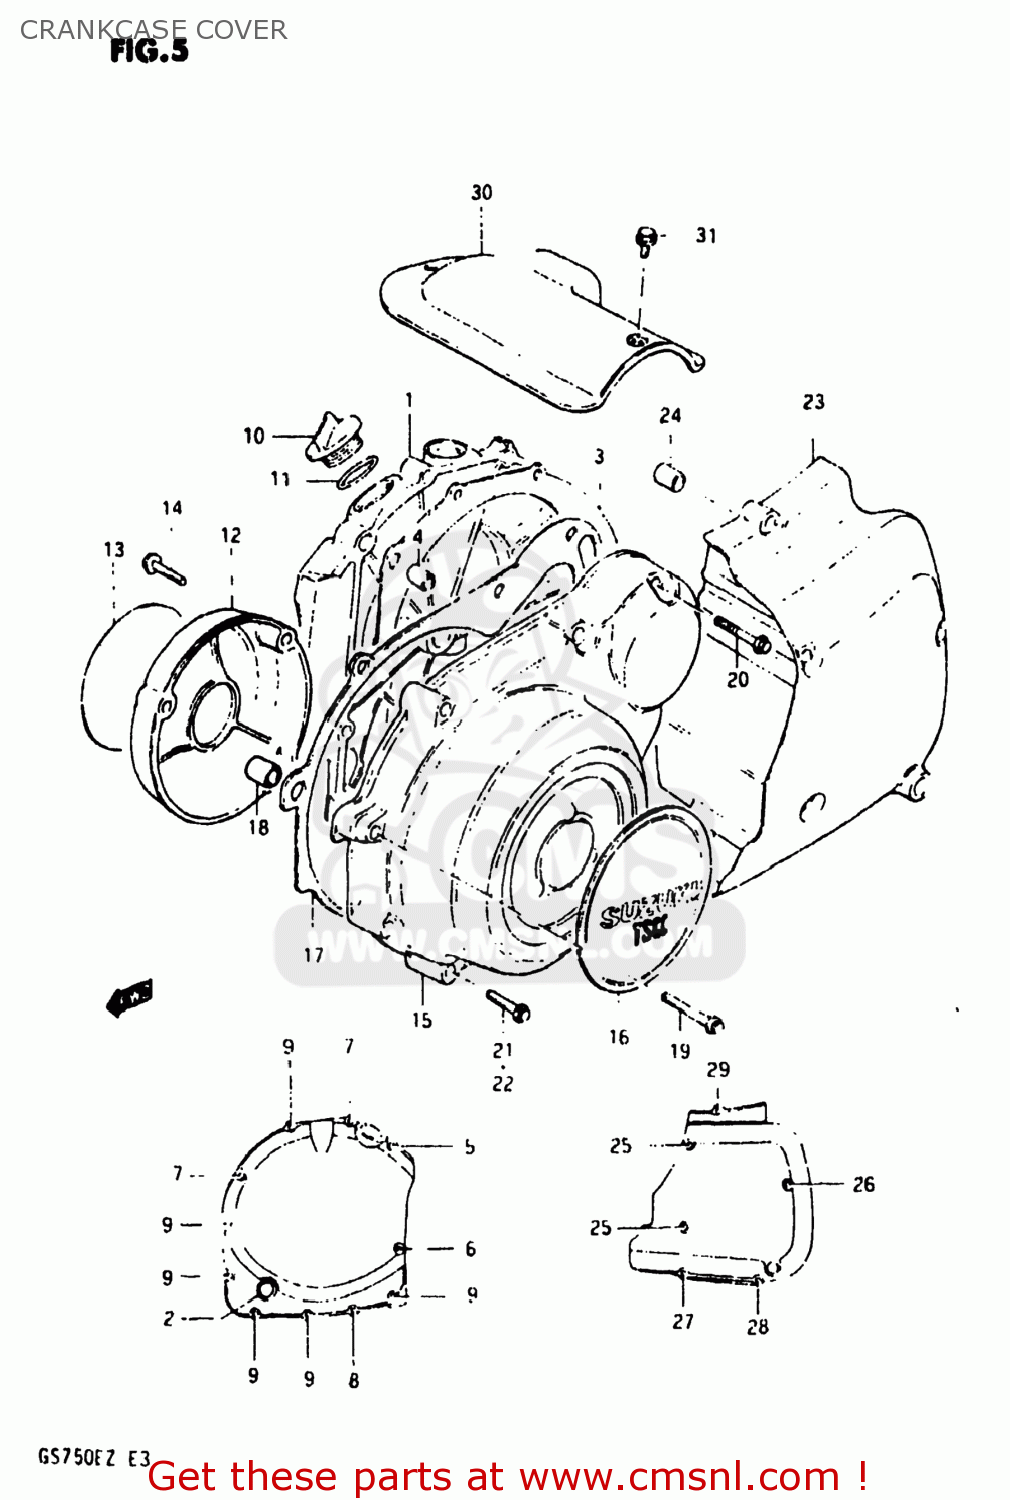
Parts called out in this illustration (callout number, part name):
1	COVER,CLUTCH
2	LENS,OIL LEVEL CHECK
3	GASKET,CLUTCH COVER (MCA)
4	PIN
5	BOLT (6X40)
6	BOLT (6X35)
7	BOLT (6X30)
8	BOLT
9	BOLT (6X20)
10	CAP
11	O RING(D:2.2,ID:32)
12	COVER,CONTACT BREAKER
13	EMBLEM
14	BOLT (5*30)
15	COVER,MAGNETO
16	EMBLEM,MAGNETO COVER
17	GASKET,MAGNETO COVER (MCA)
18	PIN
19	BOLT
20	BOLT (6X40)
21	BOLT (6X35)
22	BOLT (6X30)
23	COVER,ENGINE SPROCKET
24	PIN
25	BOLT 6X95
26	BOLT (6X85)
27	BOLT (6X70)
28	BOLT (6X55)
29	BOLT (6X30)
30	COVER,STARTER MOTOR
31	BOLT (5*8)
